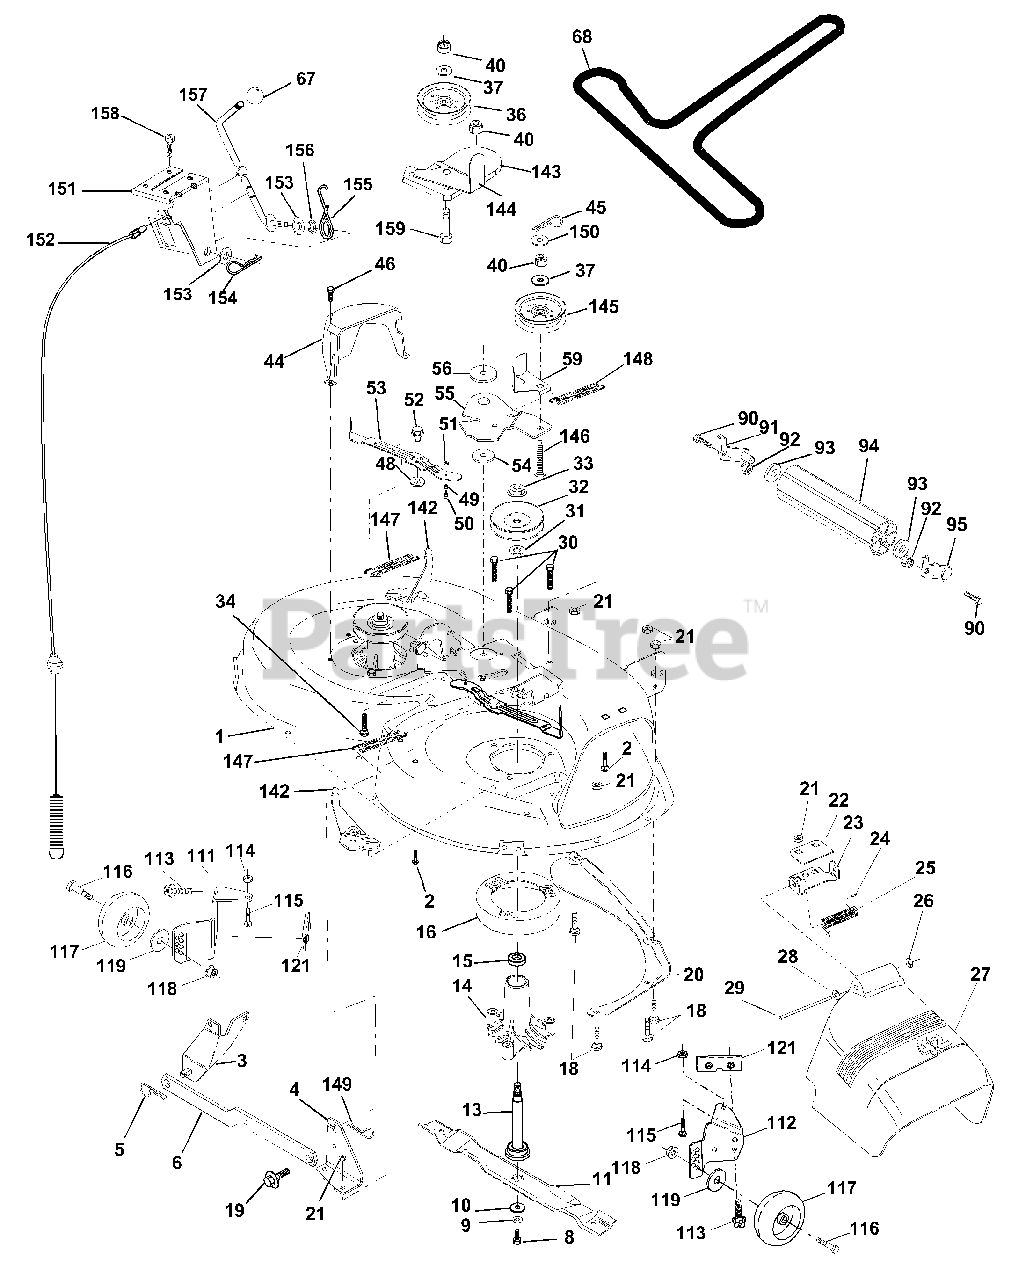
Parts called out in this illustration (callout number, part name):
1	Mower Deck Assembly, 42"
2	Bolt
3	Bracket Asm Fr. Sway Bar 3/42
4	Bracket Asm Deck 42" Sway Bar
5	Retainer Spring
6	Arm, Suspension, Rear
8	Bolt 3/8-24 x 25 Grade 8 patched
9	Washer, Lock
10	Washer,Hardened
11	Blade
13	Shaft Assembly, Mandrel, Vented
14	Housing, Mandrel, Vented
15	Bearing, Ball, Mandrel
16	Stripper, Vented Mower Deck
18	Bolt, Carriage 5/16-18 x 5/8
19	Bolt, Shoulder
20	Baffle, Vortex
21	Nut
22	Stiffener Bracket
23	Bracket, Deflector Mower 42"
24	Cap, Sleeve 80 x 112 Blk Mower
25	Spring, Torsion, Deflector 2 52
26	Nut, Push Phos & Oil
27	Shield, Deflector 42" Blk
28	Washer 11/32 x 5/8 x 16 Gauge
29	Rod, Hinge 42" 6 75 W/G
30	Screw Thdrol Washer Head
31	Washer, Spacer Mower Vented
32	Pulley, Mandrel
33	Nut, Toplock 9/16
34	Bolt
35	Fastener, Christmas Tree
36	Pulley, Idler, Flat
37	Washer 13/32 x 13/16 x 16 Gauge
40	Nut
44	Guard, Mandrel, LH
45	Retainer
46	Screw, Thdrol 1/4-20 x 5/8 T
48	Washer,Hardened
49	Roller Assembly, Cam Follower
50	Bolt, Shoulder #10-24 Grade 5
51	Locknut
52	Bolt, Shoulder 5/16-18 UNC
53	Arm Assembly, Pad, Brake
54	Washer,Hardened
55	Arm, Idler
56	Spacer, Retainer
59	Guard TUV Idler
67	Knob
68	V-Belt, 42" Mower
90	Bolt Fin Hex 3/8-16 Unc x 1
91	Bracket Asm Noseroller Lh
92	Nut Lock Hex w/Ins. 3/8-16 Unc
93	Washer 17/32 x 7/8 x 16 Ga.
94	Roller Nose 38-50"
95	Bracket Asm. Noseroller Rh
111	Bracket Gauge Wheel Lh
112	Bracket Gauge Wheel Rh
113	Screw Tapping 5/16-18 Unc
114	Nut Keps 5/16-18unc
115	Bolt Carr 5/16-Unc x 1/2
116	Bolt Shld
117	Wheel Gauge Blk
118	Nut Centerlock 3/8-16unc
119	Washer 3/8 x 7/8 x 14 Ga.
121	Bracket Extruded Gauge Wheel
142	Arm Spring Brake Mower
143	Bracket Arm Idler 42"
144	Keeper Belt 42" Clutch Cable
145	Pulley Idler Flat
146	Bolt Carriage Idler
147	Spring Extension
148	Spring Return Idler
149	Retainer Spring Yellow
150	Washer 9/32 x 3/4 x 16 Ga.
151	Bracket Clutch Cable
152	Clutch Cable 42"
153	Washer Flat 3/8" Type B
154	Spring Retainer
155	Spring Retention LVR CLTCH CAB
156	Spacer Clutch Cable
157	Rod Clutch Cable 3/8"
158	Screw Hex Thd Cut 1/4-20 x 5/8
159	Bolt Rdhd Sqn 3/8-16 UNC x 1-3/4
